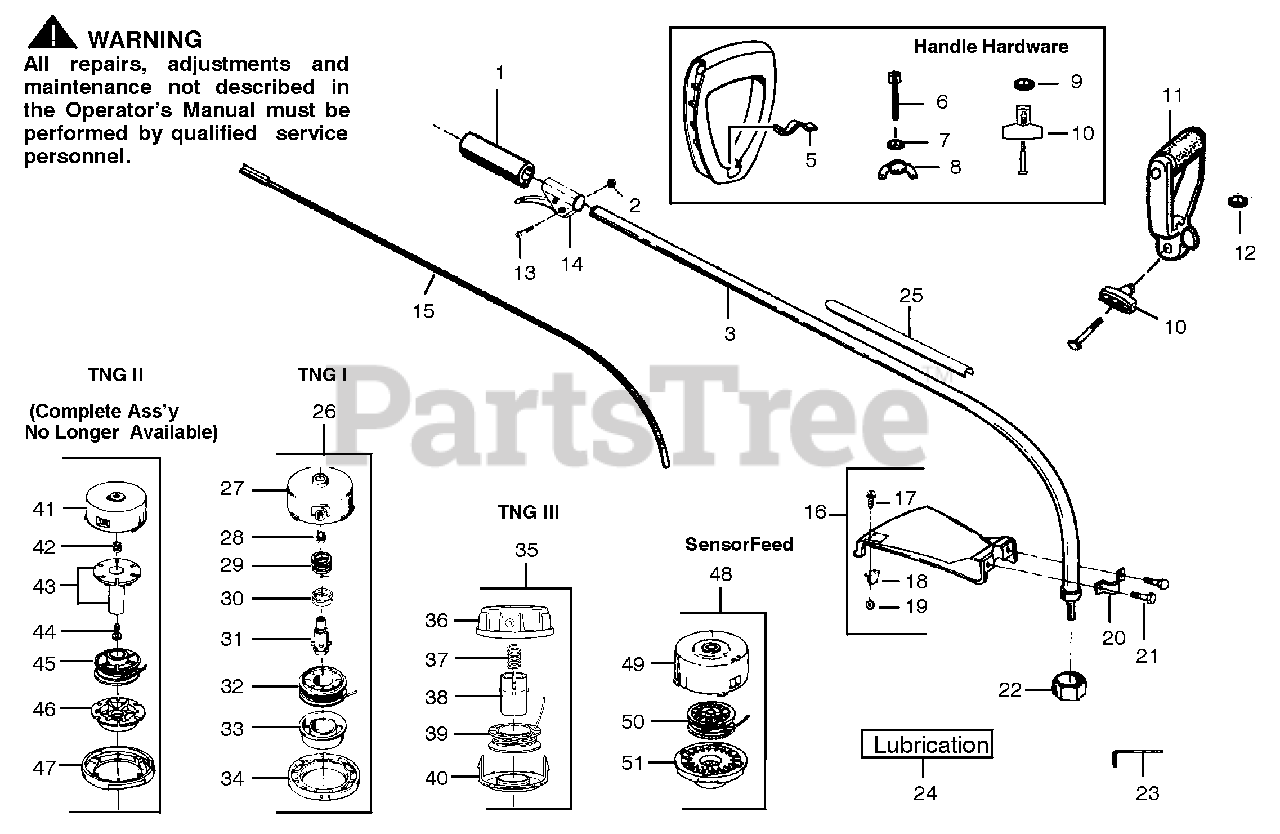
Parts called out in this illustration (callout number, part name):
3	Drive Shaft Hsg (20T, 40)
10	"T" Handle Kit
14	Throttle Hsg Ass'y
14	Drive Shaft (40)
16	Shield Kit Ass'y (40, 20T)
18	Line Limiter (20, 20T, 40, 50)
19	Locknut
20	Shield Bracket (20T, 40)
22	Dust Cup
23	Hex Wrench (5/32)
24	Shaft Lubrication
25	Shaft Warning Decal
26	Cutting Head Ass'y
27	Hub Ass'y
28	Line Saver
30	Spring Cap
31	Drive Gear
32	Spool w/Line
33	Release Button
34	Cutting Head Ass'y (w/3/8" arbor 40,40T)
34	Hub Ass'y (w/3/8" arbor 40,40T)
38	Release Button
39	Spool w/Line
41	Hub Ass'y
43	Locking Plate Kit
45	Spool w/Line
46	Release Button
48	Cutting Head Ass'y
49	Hub Ass'y
50	Spool w/Line
